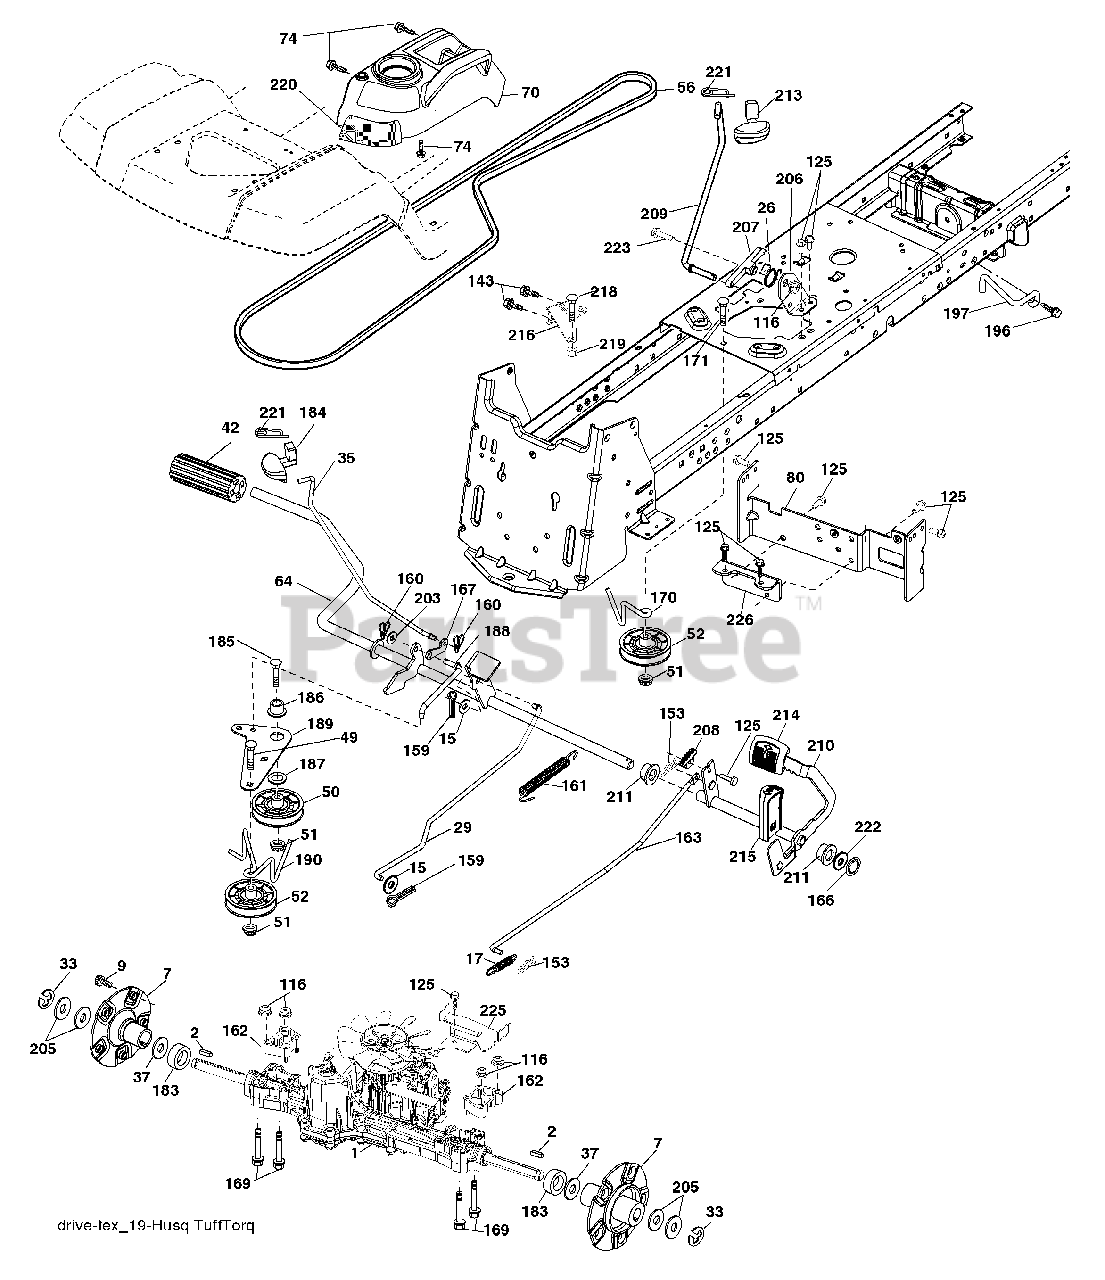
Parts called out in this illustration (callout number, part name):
1	TUFFTORQ K46
2	Key 1/4 x 2.5
7	Hub Asm. Wheel
9	Bolt Hub Wheel
15	Washer 13/32 x 13/16 x 16 Ga.
17	Spring, Brake
26	Spring Return Cruise
29	Rod, Brake
35	Rod, Brake, Park
42	Cover, Foot Pedal
50	Pulley Idler Flat
51	Lock Nut 3/8-16
52	Idler V-Groove 910" Offset
56	V-Belt, Drive
64	Shaft Asm. Pedal Brake Control
70	Control Asm.
74	Screw 1/4 x 1/2
80	Strap Torque
116	Nut Lock Hex Flange 5/16-18
125	Screw 5/16-18 x 3/4
143	Screw Thdrol 5/16-18 x 1/2
153	Retainer Spring
159	Pin Cotter 1/8 x 3/4
160	Retainer Clip
161	Spring, Return, Clutch
162	Spacer Transaxle
163	Rod Pedal Control
166	Nut Push .625
167	Latch Brake Parking
169	Bolt Hex Flghd 5/16-18 x 3.75
170	Keeper Belt Centerspan
171	Bolt RDHD SQNK 3/8-16UNC x 2
183	Spacer Split
184	Handle Parking Brake
185	Bolt Rdhd Sqnk 3/8-16 x 2-1/2
186	Spacer Retainer
187	Washer
188	Link Clutch Ground Drive
189	Bellcrank Ground Drive
190	Keeper Bellcrank Ground Drive
196	Screw 3/8-16 x 1
197	Bracket Clutch Anti-Rotation
203	Washer 11/32 x 11/16 x 16 Ga.
206	Bracket Mount Latch Cruise
207	Latch Control Cruise
208	Gear Sector Control Cruise
209	Rod Control Cruise
210	Rocker Asm. Pedal Control
211	Bearing Nylon
213	Knob Control Cruise
214	Pedal Forward
215	Pedal Reverse
216	Bracket Pulley Idler
218	Bolt Fin Hex 5/16-18 unc x 1-1/4
219	Spacer Fender
220	Reflector RH
221	Retainer Spring Clip Handle
222	Washer 21/32 x 1-1/4 x 10 Ga.
223	Bolt Fin Hex 5/16-18 unc x 1.25
225	Keeper Belt Trans.
226	Bracket Mount Touque
